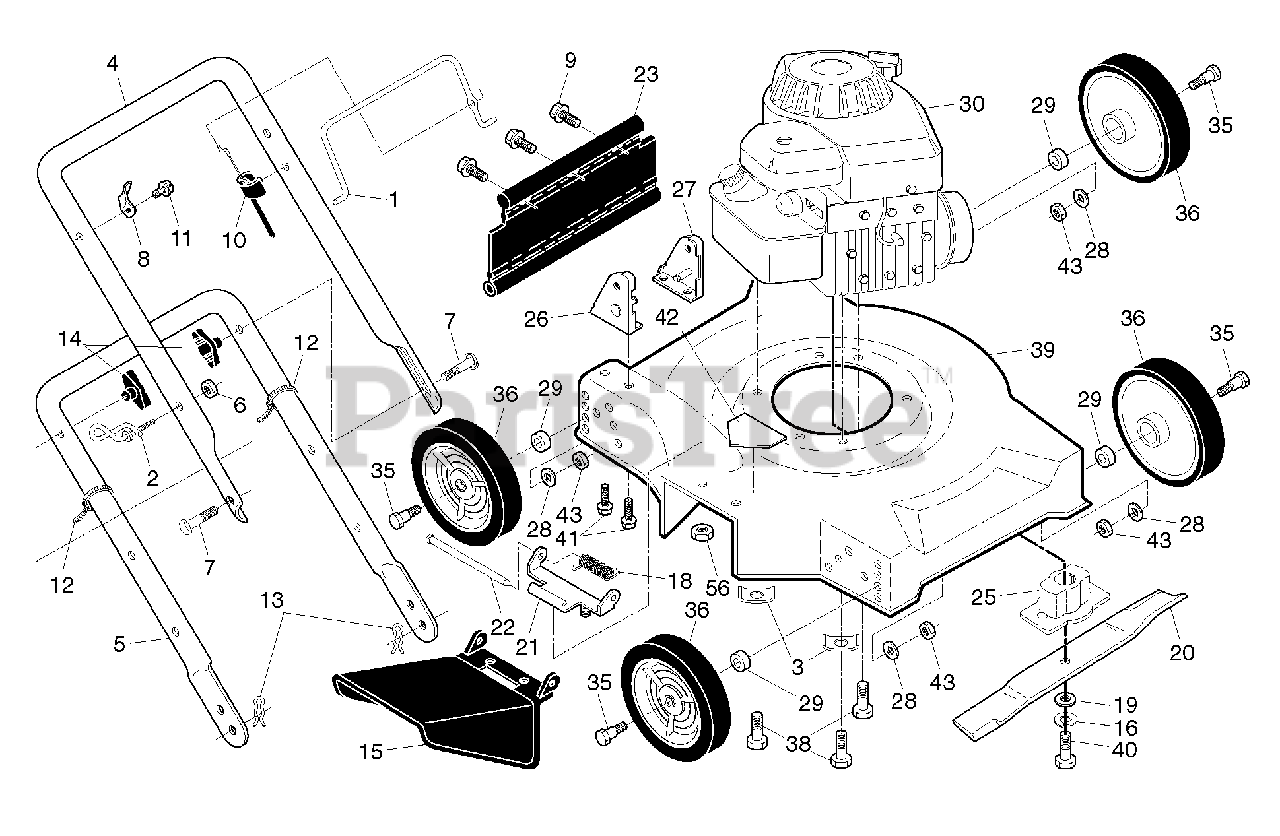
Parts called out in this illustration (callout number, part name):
1	BAIL.CONT.D.STRAIGHT.PUSH.BLK
2	GUIDE.ROPE.STD.BLK.ZIN
3	WASHER.ENGINE.BZP
4	HANDLE.UPPER.FGD/PUSH.BLACK
5	LOWER HANDLE
6	NUT
7	BOLT, HANDLE 5/16-18X1.75
8	BRACKET.UPSTOP.RT
9	SCREW.HEX.WASH.HD.TAPPING
10	ENG ZONE CNTRL CB
12	TIE GUIDE
13	HAIRPIN COTTER
14	KNOB.WING.PLASTIC.BLACK
15	GUARD.DISCHARGE.ECON.BLK.US/CE
18	SPRING.SIDE.DISCHARGE
19	WASHER,HARDEN
20	Mower Blade, 20" Mulching
21	HINGE DEFLECTOR
22	HINGE ROD
25	BLADE ADAPTOR
26	HANDLE BRACKET ASM. RH
27	HANDLE BRACKET ASM. LH
28	WASHER
29	SPACER.WHEEL.390.X1.0X.380.RTA
35	AXLE BOLT
36	WHEEL.7X1.5.DMD.GS.3SPK.SYEL.1
38	BOLT 3/8-16X1-1/8
40	SCREW, HEX HD 3/8-24 X 1-3/8
41	SCREW.5/16-18X3/4
42	No Step Decal
43	LOCKNUT
56	LOCKNUT.NYLOC.1/4-20
